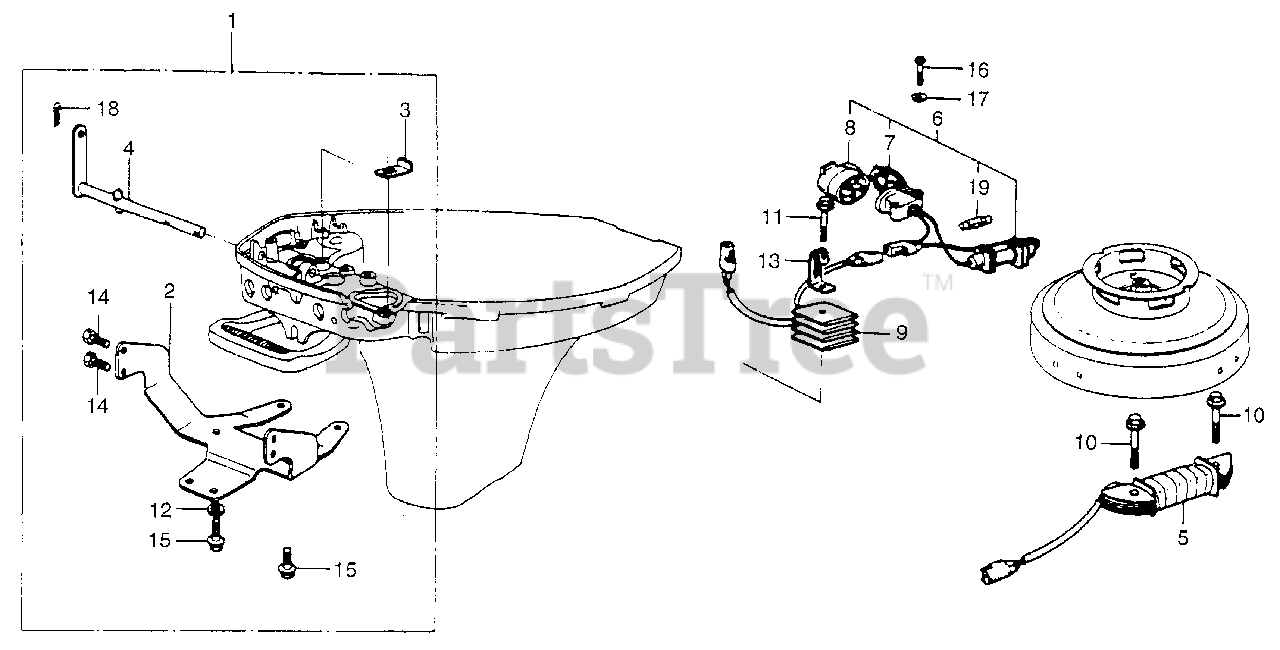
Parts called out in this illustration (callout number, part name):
1	CONTROL KIT, REMOTE
2	BRACKET, STEERING
3	STOPPER, THROTTLE ARM
12	WASHER, PLAIN (6MM)
14	BOLT, HEX. (5X10)
15	BOLT, HEX. (6X12)
18	PIN, LOCK (6MM)
